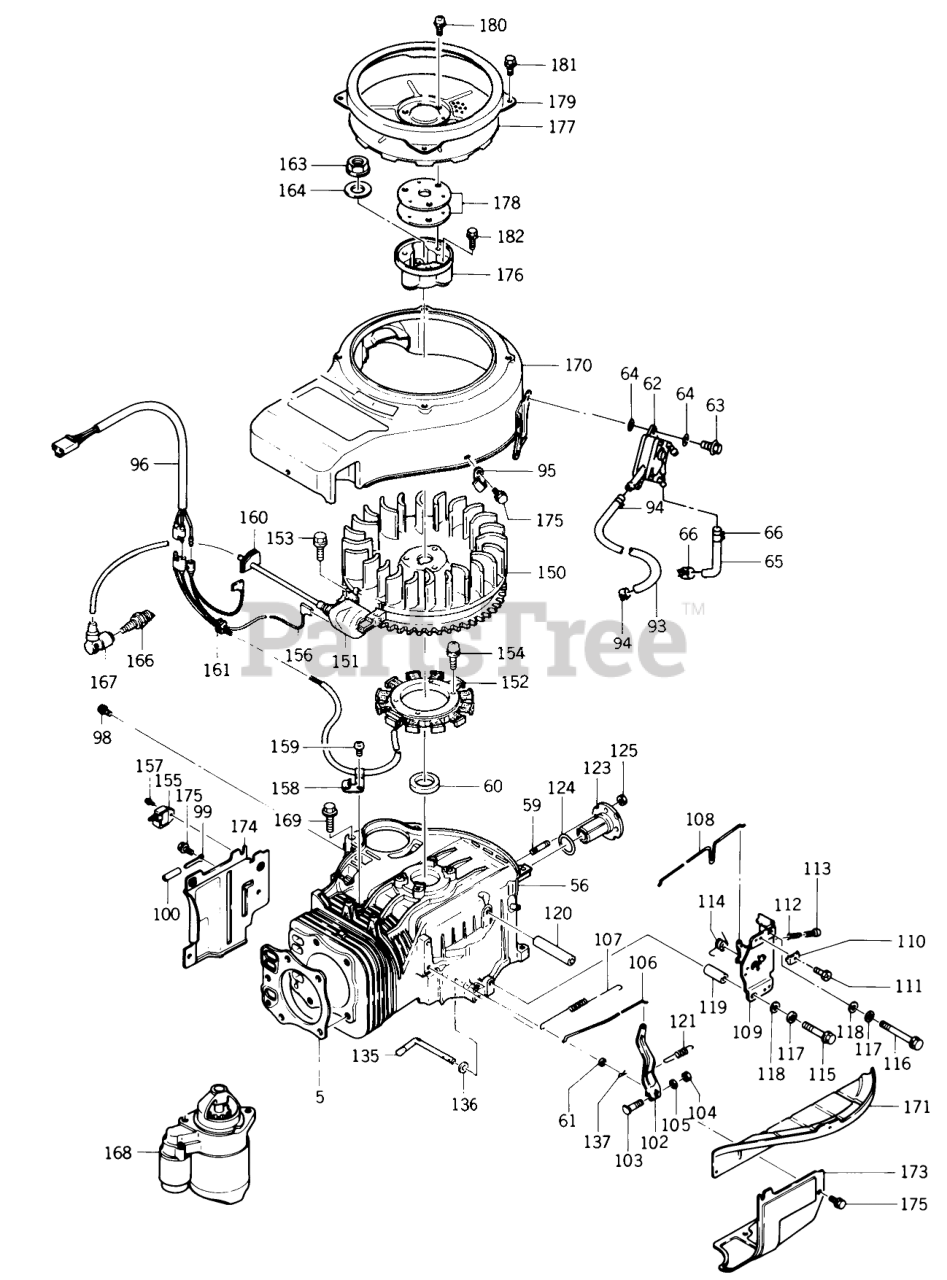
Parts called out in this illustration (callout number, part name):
5	GASKET HEAD
56	CASE-CRANK
60	SEAL OIL
61	SEAL-OIL, VC (6X10X2.5)
62	PUMP-FUEL ASSY
63	Bolt
64	WASHER
95	CLAMP
96	HARNESS
98	BOLT-FLANGED
99	CLAMP
102	ARM ASS'Y
103	Bolt
104	NUT 6MM
105	Washer
106	LINK GOVERNOR
107	SPRING-LINK
108	LINK CHOKE
109	PANEL-CONTROL
110	CLAMP
112	SPRING
113	SCREW PAN HEAD 4X25
114	SPRING
115	BOLT (6 X 50)
116	BOLT (6 X 90)
117	WASHER-SPRING 6MM
118	WASHER, CLUTCH
119	COLLAR
120	COLLAR
121	SPRING
123	SHAFT
124	O-RING
125	Nut
135	ARM-PIVOT
136	WASHER-PLAIN 6MM
137	Pin
150	FLYWHEEL ASS'Y
151	COIL IGNITION
152	COIL-CHARGING
154	SCREW (6 X 25)
155	IGNITER
156	LEAD WIRE
157	SCREW (4 X 8)
158	CLAMP
159	SCREW
160	GROMMET
161	GROMMET
164	WASHER
166	SPARK PLUG
167	CAP-SPARKPLUG
168	Starter Assembly See Section 10-7 For Complete Parts Breakdown
168	Starter Assembly (See Section 10-6 for complete parts breakdown)
169	BOLT (8 X 35)
170	HOUSING-FAN
171	HOUSING-FAN
173	SHROUD
174	SHROUD
175	Bolt 6 x 12
176	BRACKET
177	SCREEN
179	GUARD
180	CLAMP
181	Bolt
182	BOLT (8 X 20)
